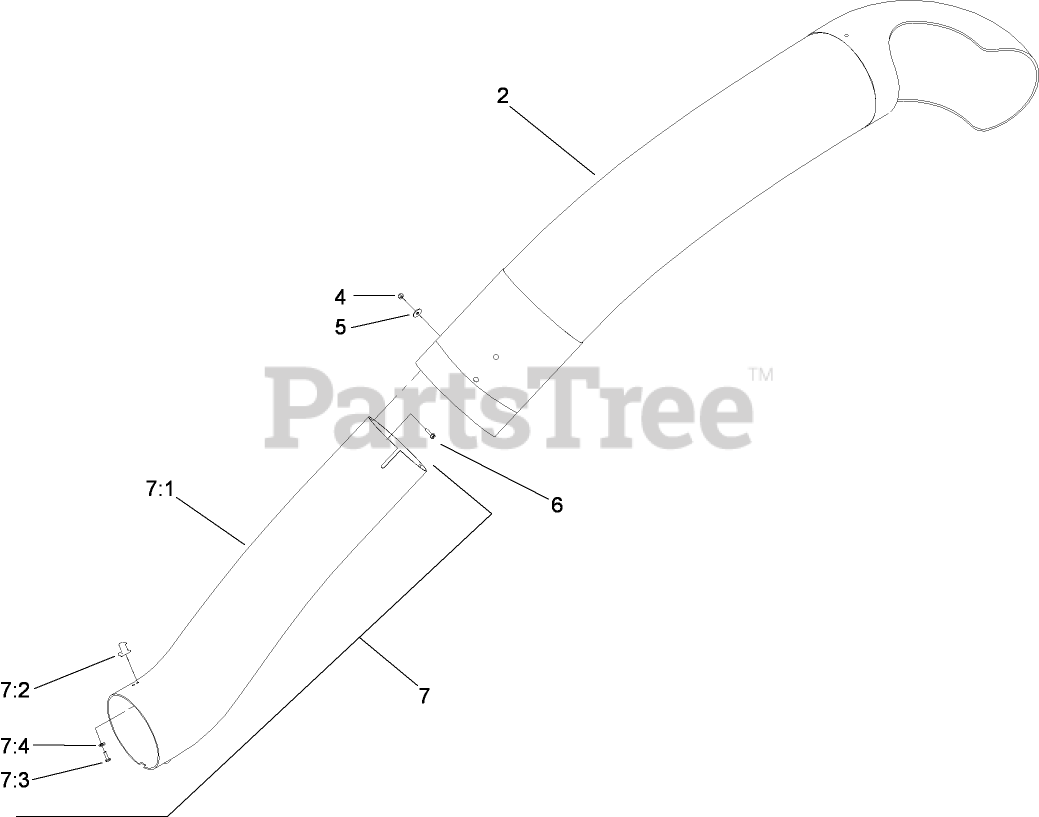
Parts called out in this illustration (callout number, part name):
2	TUBE-UPPER
4	NUT-LOCK, NI
5	WASHER-FLAT
6	SCREW-HWH
7	LOWER TUBE ASM
7:1	TUBE-LONG, LOWER
7:2	LATCH-KEEPER
7:3	SCREW-PPH
7:4	WASHER-FLAT
